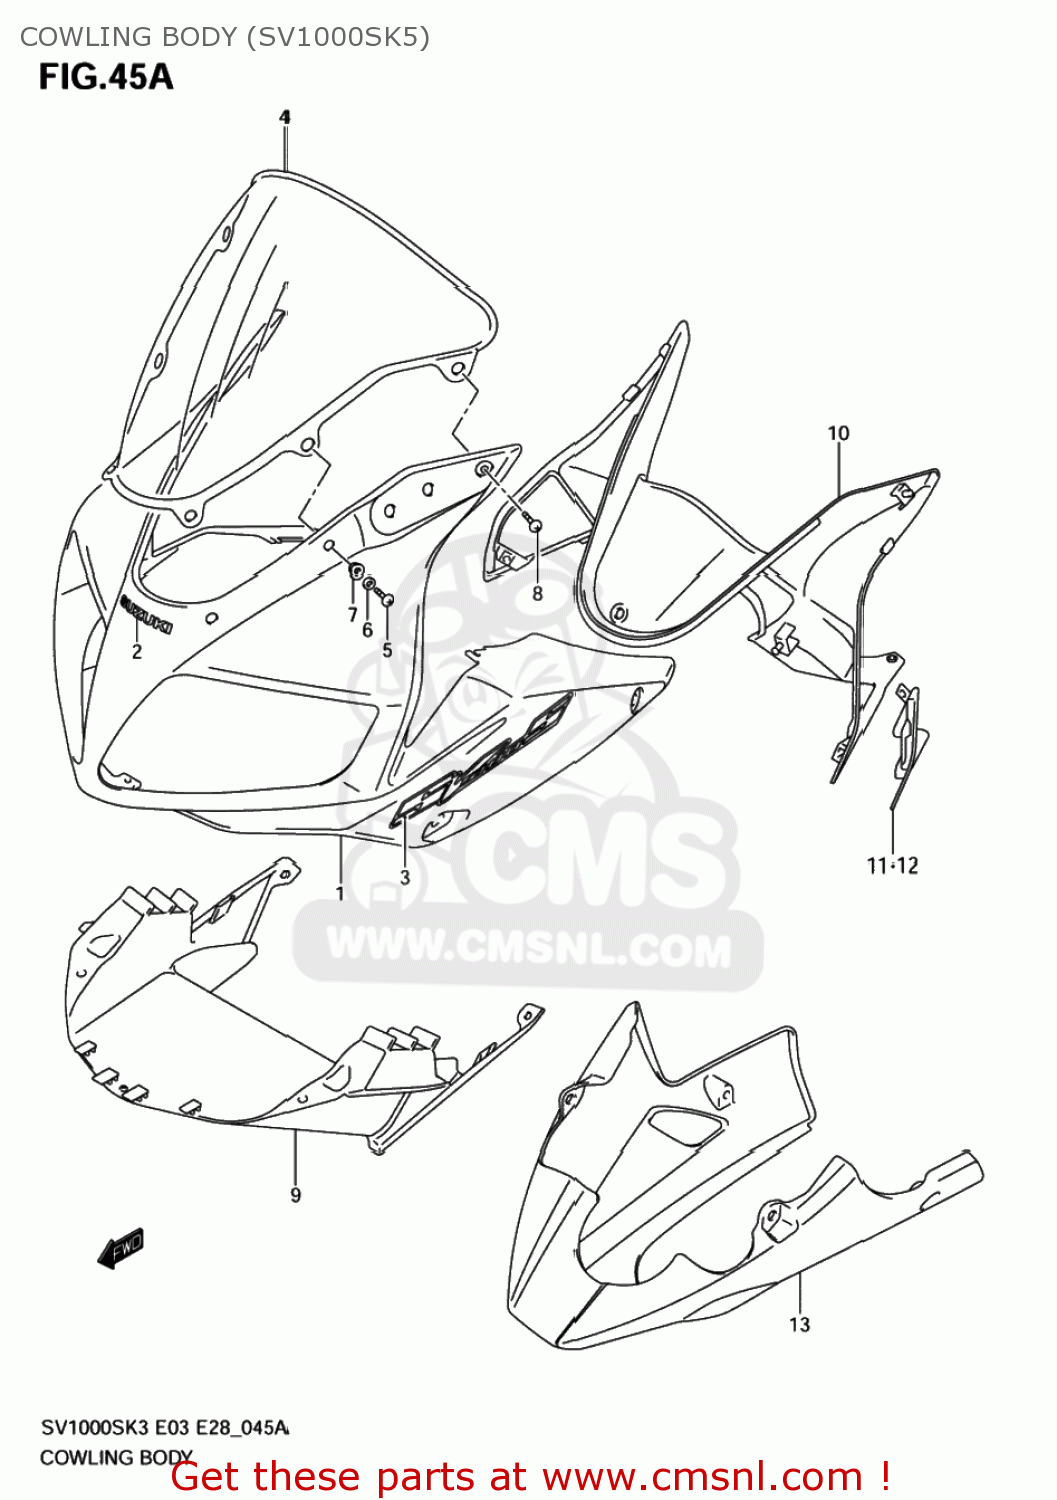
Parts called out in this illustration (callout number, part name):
1	COWLING ASSY,BODY
2	EMBLEM,SUZUKI
3	EMBLEM,BODY COWL
4	WINDSCREEN COM
5	SCREW(5X14)
6	WASHER
7	NUT
8	SCREW(5X16)
9	COVER,COWLING INNER
10	PANEL,METER
11	LID,METER PANEL,R
12	LID,METER PANEL,L
13	COWLING,UNDER
